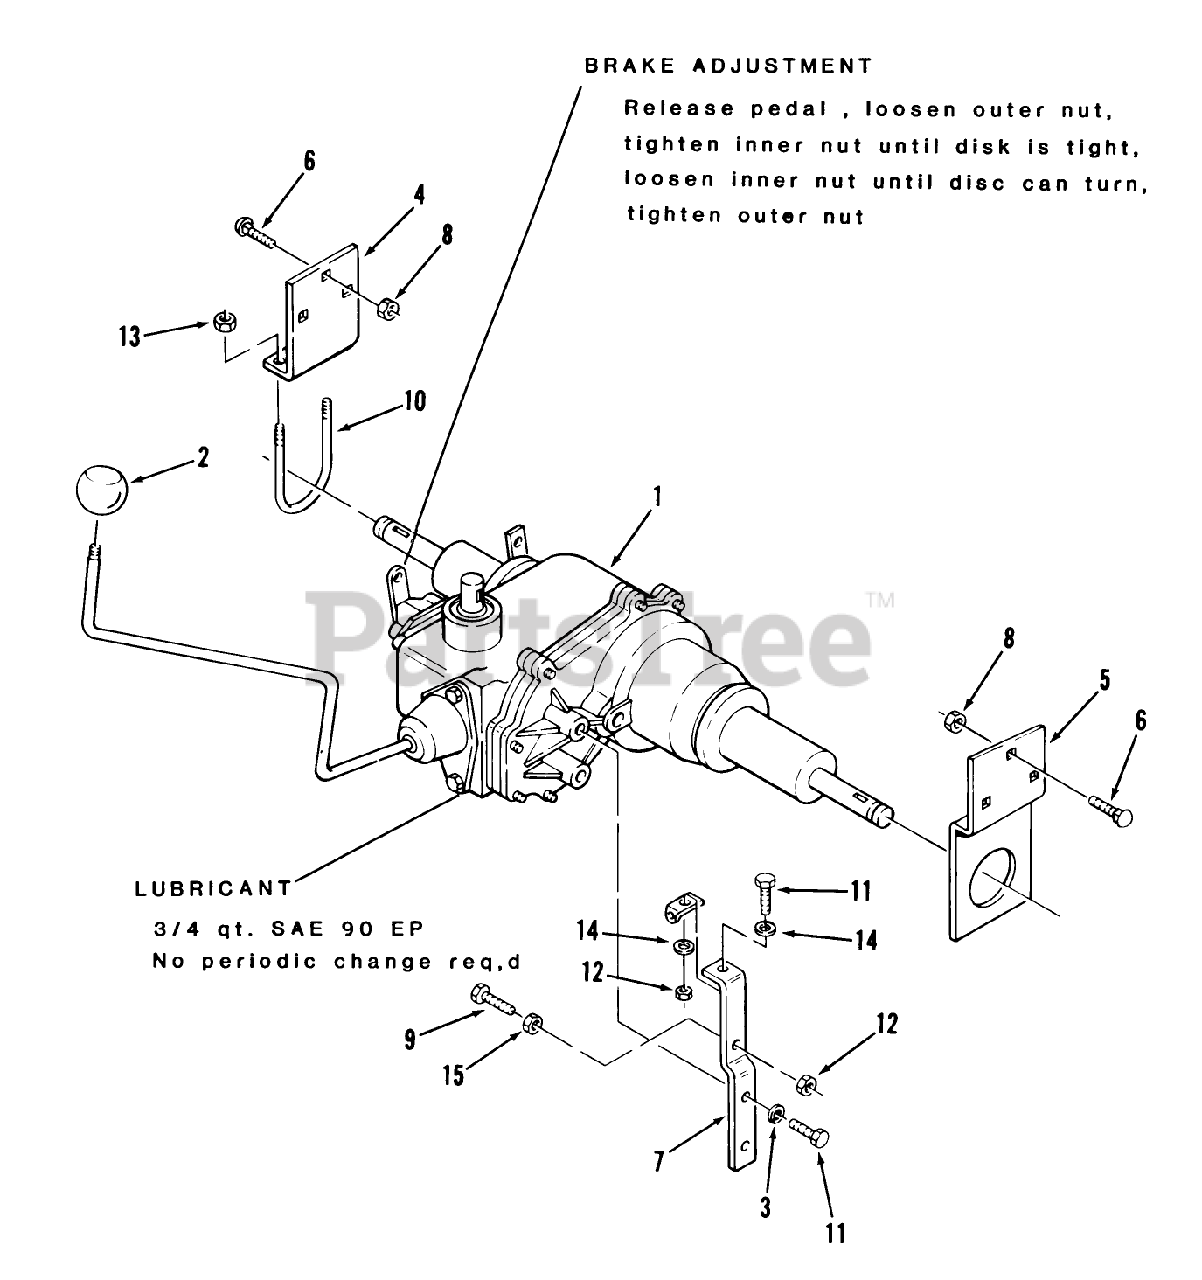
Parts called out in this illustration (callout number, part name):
1	ORDER FROM PEERLESS
6	CARRIAGE BOLT -4
14	WASHER 5/16 SAE
